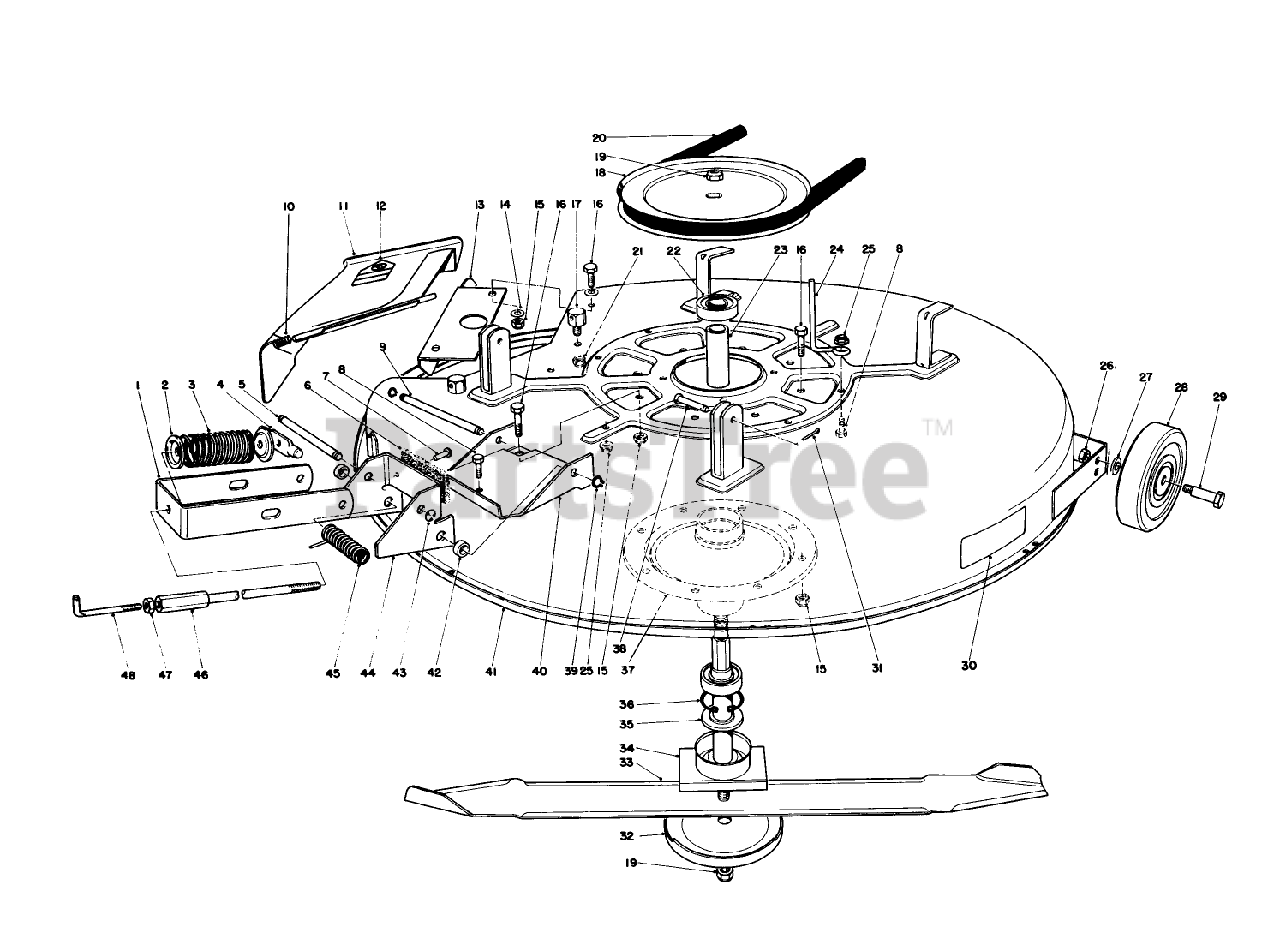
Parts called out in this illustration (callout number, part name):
2	RETAINER-SPR. TOP
3	SPRING-COMPRESSION
4	SHAFT-DECK ADJ.
6	BRAKE PAD
8	SCREW-HH
9	CLEVIS PIN
10	SPRING
11	DEFLECTOR ASM
14	WASHER-PLAIN
15	NUT-LOCK, NI
16	SCREW-HH
17	POST-PIVOT
18	PULLEY
19	NUT-SPECIAL
20	V-BELT, DECK
21	NUT-LOCK, SIDE
22	BEARING-BALL
24	BELT GUIDE
25	NUT-LOCK, HHF
27	WASHER-FLAT
31	PIN-COTTER
34	SPINDLE SHAFT WA
35	SPACER-SPINDLE
38	PIN-CLEVIS
39	RING-RETAINING
43	E-RING
45	SPRING
47	NUT-JAM
